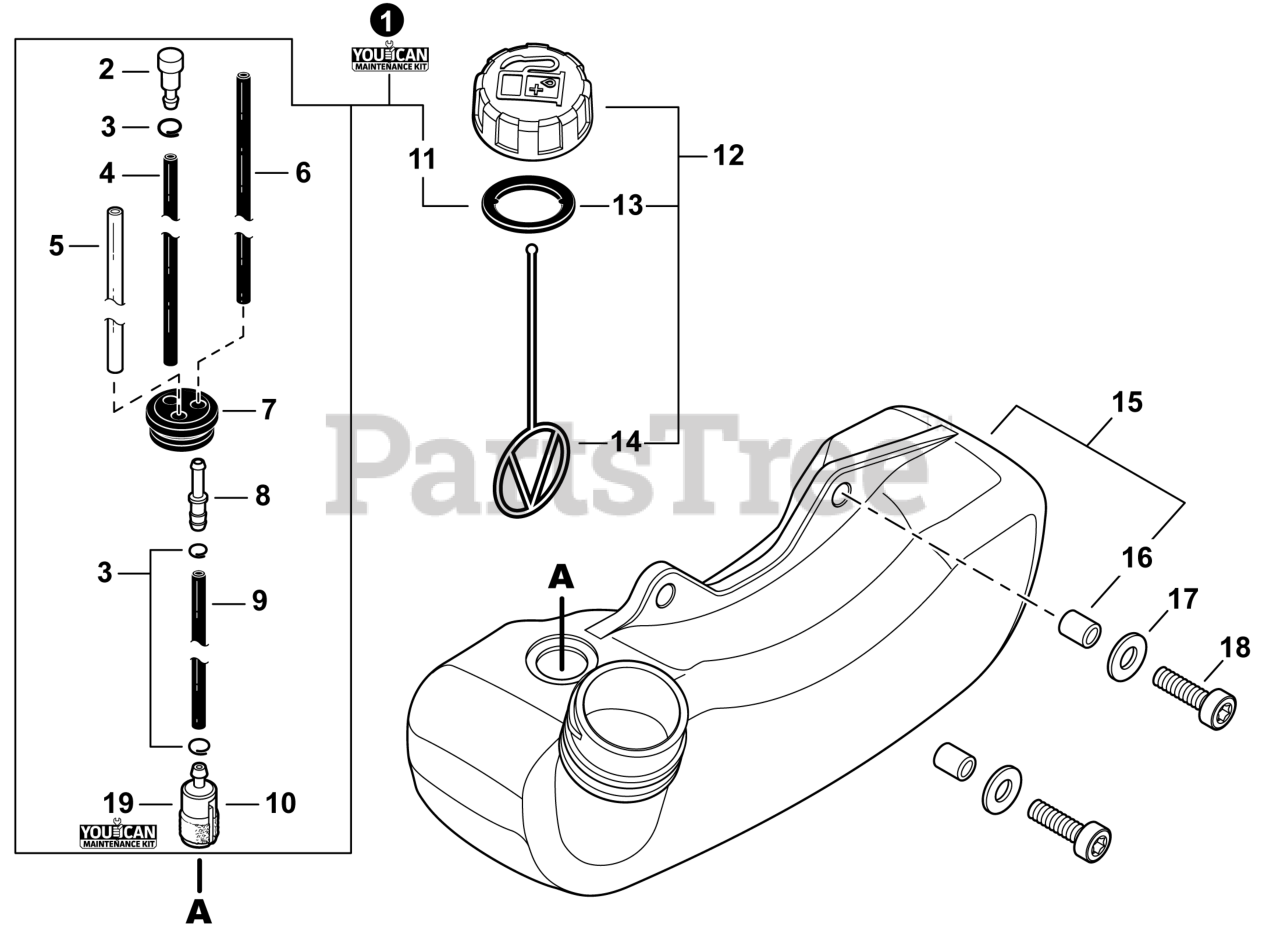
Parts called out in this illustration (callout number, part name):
1	FUEL SYSTEM KIT - YOUCANT
2	VENT ASSY
4	PIPE, FUEL 3x5x80 BLACK
5	PIPE, FUEL 3x6x85 YELLOW
6	PIPE, FUEL 3x5.5x78 BLACK
7	GROMMET, FUEL 5
8	CONNECTOR, PIPE 5x3.5
9	PIPE, FUEL 3x5x130 BLACK
10	FILTER, FUEL
11	GASKET, FUEL CAP
12	CAP ASSY, FUEL
13	GASKET, FUEL CAP
14	CONNECTOR, CAP L= 100 MM
15	TANK ASSY, FUEL
16	SPACER 6.2x7.8x6
17	WASHER 5.5x12x0.8
18	BOLT, TORX 5x16
19	TUNE-UP KIT - YOUCANT
